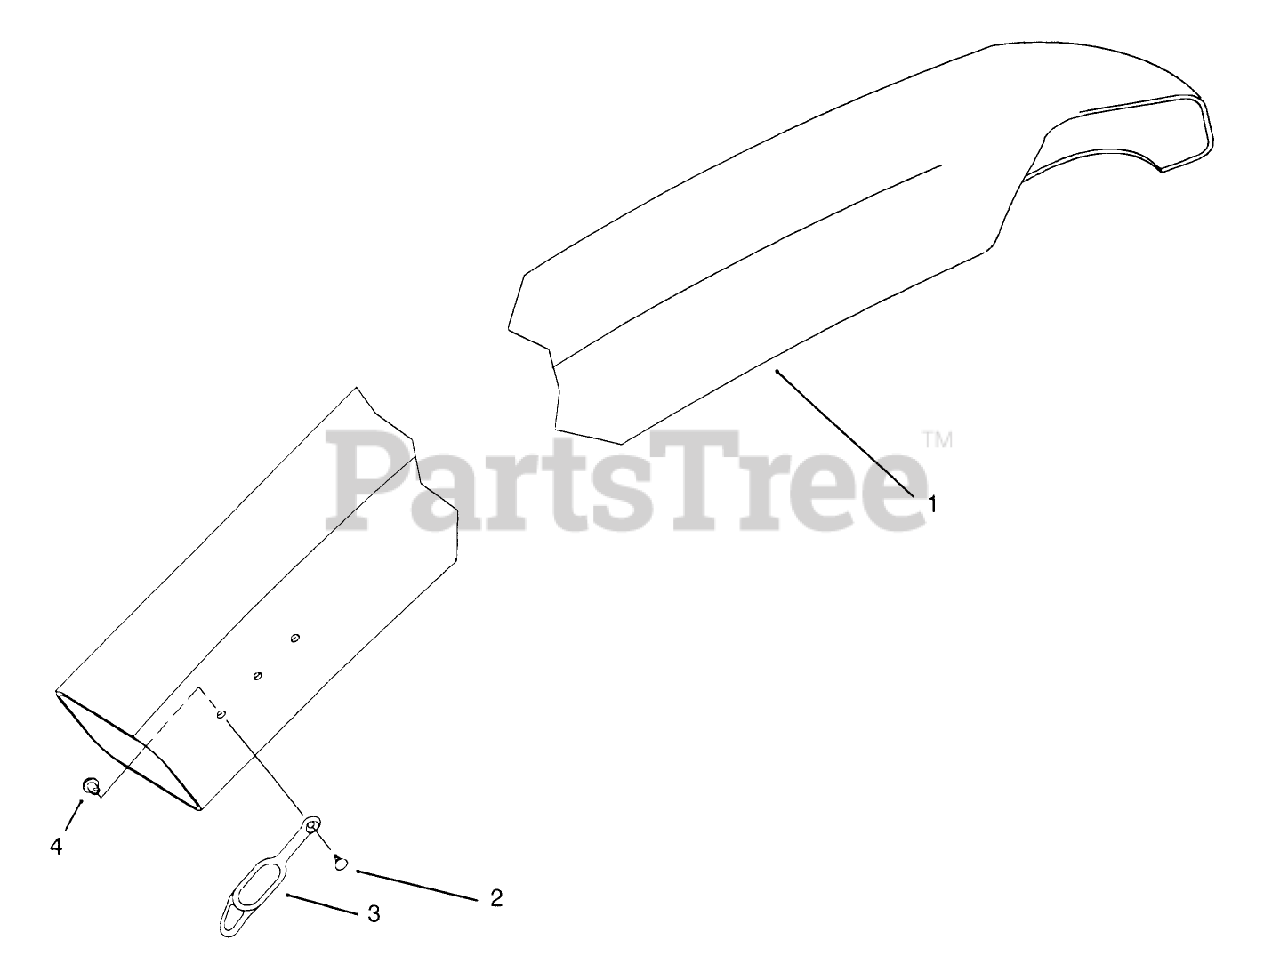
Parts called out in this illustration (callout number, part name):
1	CHUTE-DISCHARGE
2	FASTENER-PANEL
3	RETAINER-DUCT
4	SPACER-INTERLOCK
